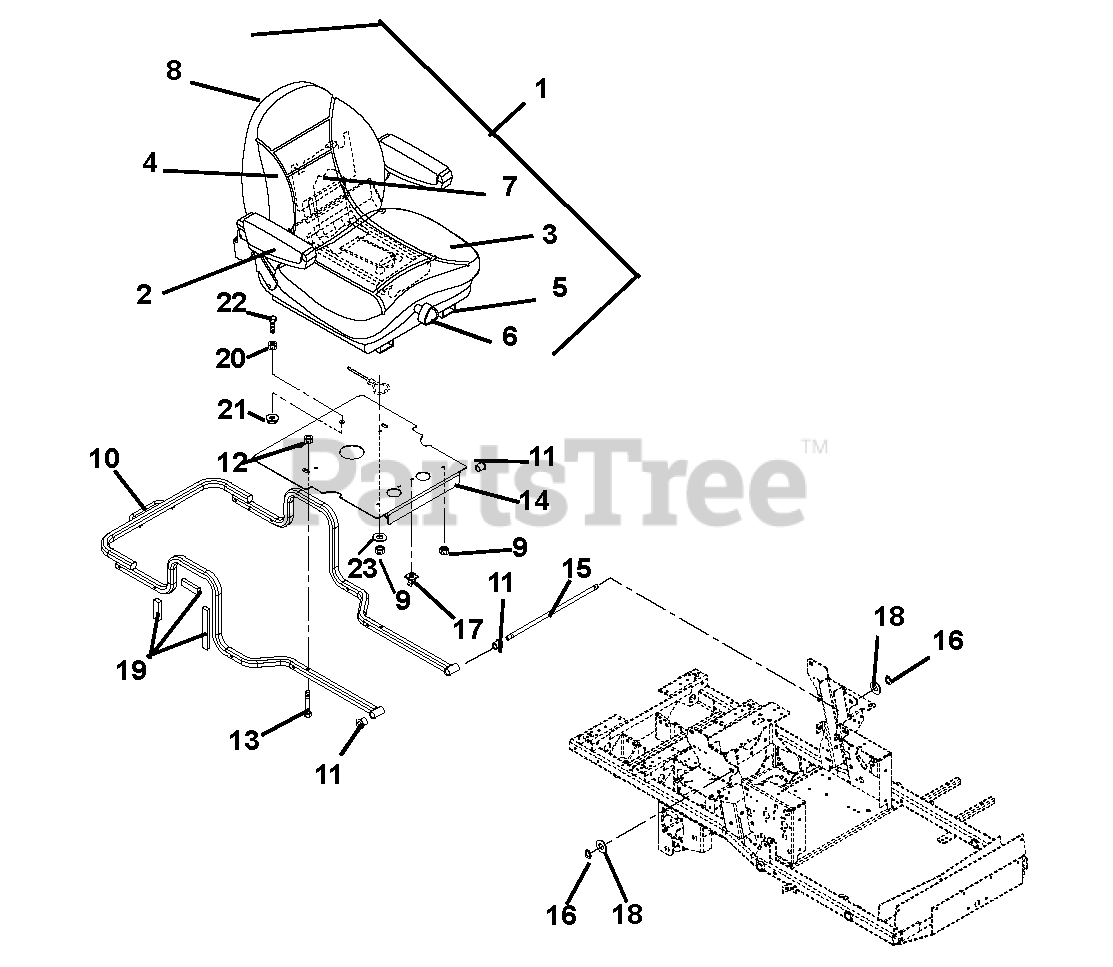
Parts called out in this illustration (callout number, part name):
1	Seat, Suspension, Light Gray
2	Kit, Arm Pad (1 per bag)
3	Kit, Seat Cushion, Light Gray
4	Kit, Back Cushion, Light Gray
5	Kit, Seat Slide
6	Kit, Seat Knob
7	Kit, Spring and Saddle
8	Kit, Seat Back Panel
9	Nut, Locking Top Flange .31-18
10	Weldment, Hood Frame
11	Bushing, Flange .515 x .750 x .745 x 1.00
12	Nut, Locking Top Flange .38-16
13	Bolt, Rib Neck .38-16 x 1.50
14	Weldment, Seat Pivot Mount
15	Rod, Seat Frame Pivot
16	Ring, Retaining External .500 x .050
18	Washer, Flat Steel .531 x 1.06 x .095
19	Tape, VHB
20	Nut, Hex .50-13
21	Nut, Locking Top Flange .50-13
22	Bolt, Hex .50-13 x 1.50
23	Washer, Flat Steel .344 x 1.125 x .135
